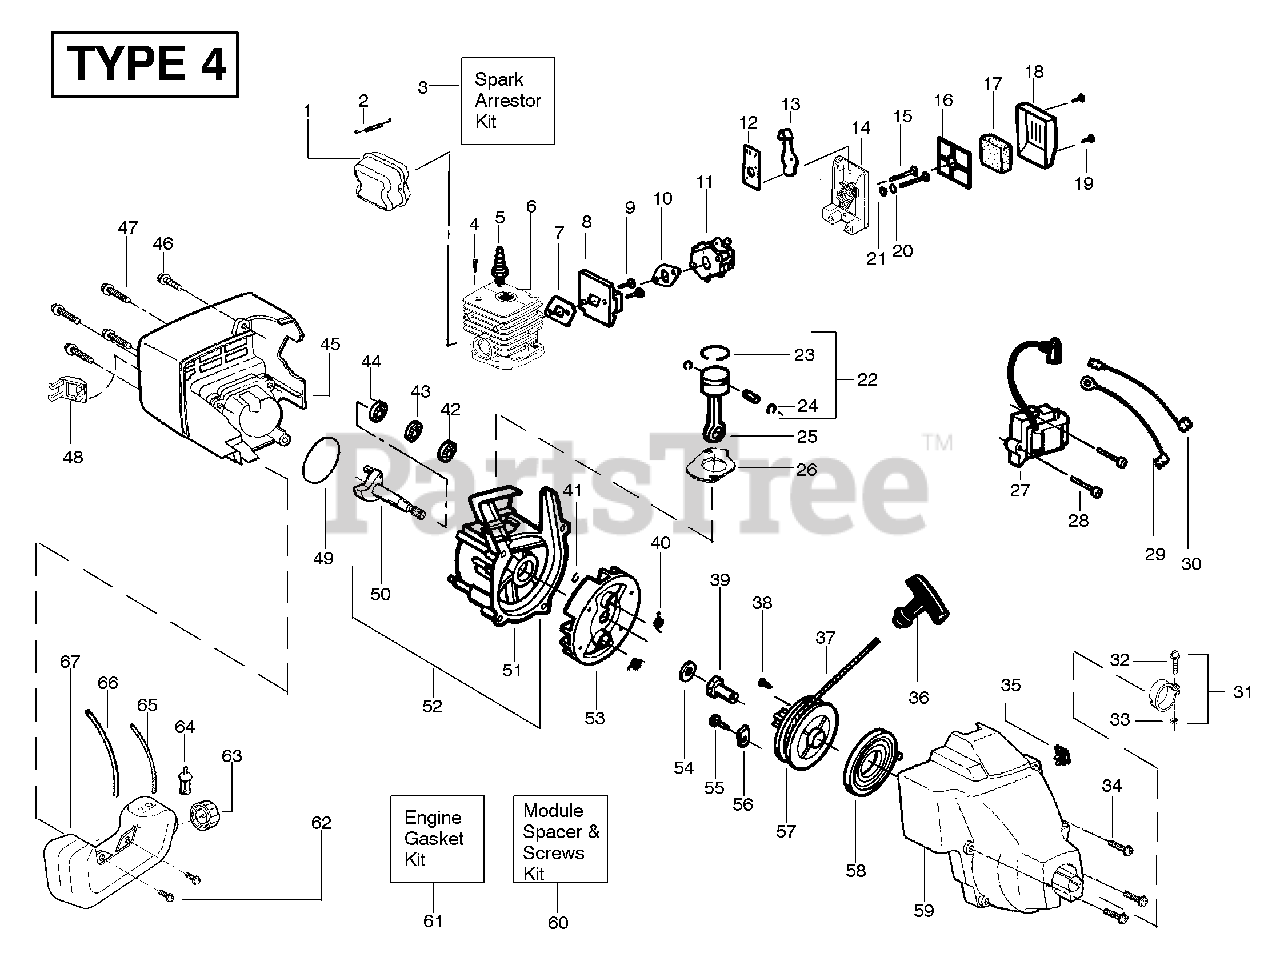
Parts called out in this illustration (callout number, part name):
1	Kit - Muffler S.A.
2	Muffler Spring
3	Kit-Spark Arrestor
4	Screw-Cylinder
5	Spark Plug (RCJ 6Y)
6	Cylinder
7	Gasket-Cyl./Carb.(kit)
8	Carb. Adaptor
10	Gasket-Carb.(kit)
11	Kit - Carb. (WA-226)
11	Kit - Carb. (C1U-W7)
11	Kit - Carb. (C1U-W7D)
12	Choke Plate Mounting
13	Choke Shutter
16	Plate - Filter Support
17	Air Filter Foam
18	Air Filter Cover
20	Spacer-Choke
22	Kit - Piston
23	Piston Ring
24	Piston Pin Retainer
25	Connecting Rod Ass'y.
26	Gasket-Cylinder(kit)
27	Ignition Module
29	Assy-Ground Wire
30	Assy-Leadwire
31	Nose Cone Clamp Ass'y.
32	Screw-Nose Cone
33	Nut-Nose Cone
34	Screw
35	Kit-On/Off Switch
36	Starter Handle
37	Kit - Rope
39	Drive Coupling
40	Starter Dog Spring
41	Retain. Ring-C'shaft
42	Outer Bearing
43	Kit-C'case Seal
44	Inner Bearing
47	Screw
48	Guard-Muffler
49	O-Ring-C'case(kit)
50	Assy-Crankshaft
51	Kit-Crankcase Ass'y.
52	C'case & C'shaft Assy.
53	Flywheel Ass'y.
54	Washer-Flat
56	Retainer-Can
57	Starter Pulley Kit
58	Starter Spring
59	Kit-Fan Hsg/Shroud
60	Kit-Module Spacer & Screws
61	Kit-Engine Gasket
62	Retainer
63	Assy-Fuel Cap
64	Assy-Fuel Pickup
65	Kit-Fuel Line (Small)
66	Kit-Fuel Line (Large)
67	Assy-Fuel Tank
